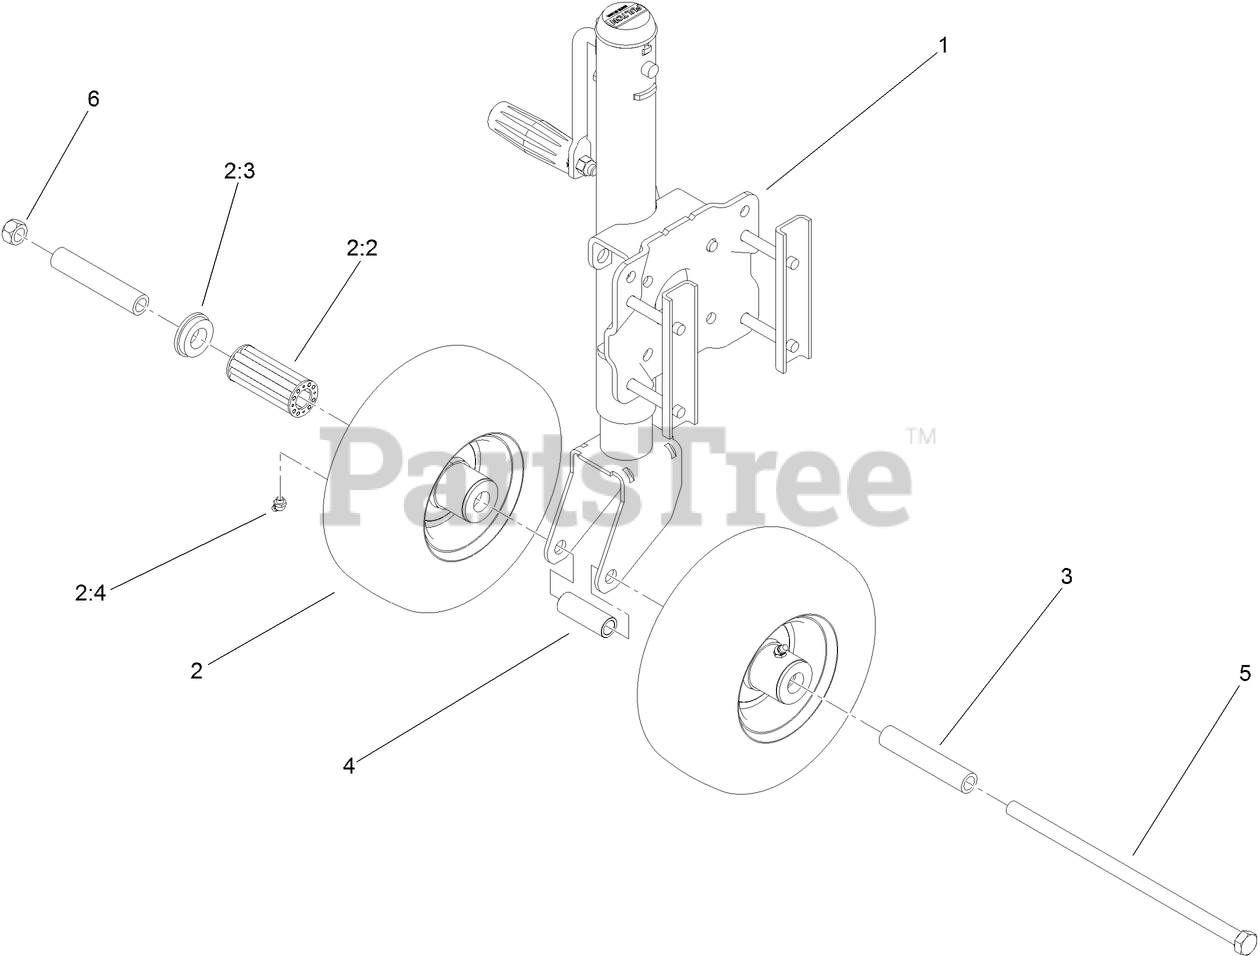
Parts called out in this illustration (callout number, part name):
1	JACK-TRAILER
2	WHEEL AND TIRE ASM
2:2	BEARING-ROLLER
2:3	BUSHING
2:4	FITTING-GREASE
3	BUSHING-SPANNER
4	SPACER
5	SCREW-HH
6	NUT-HEX
